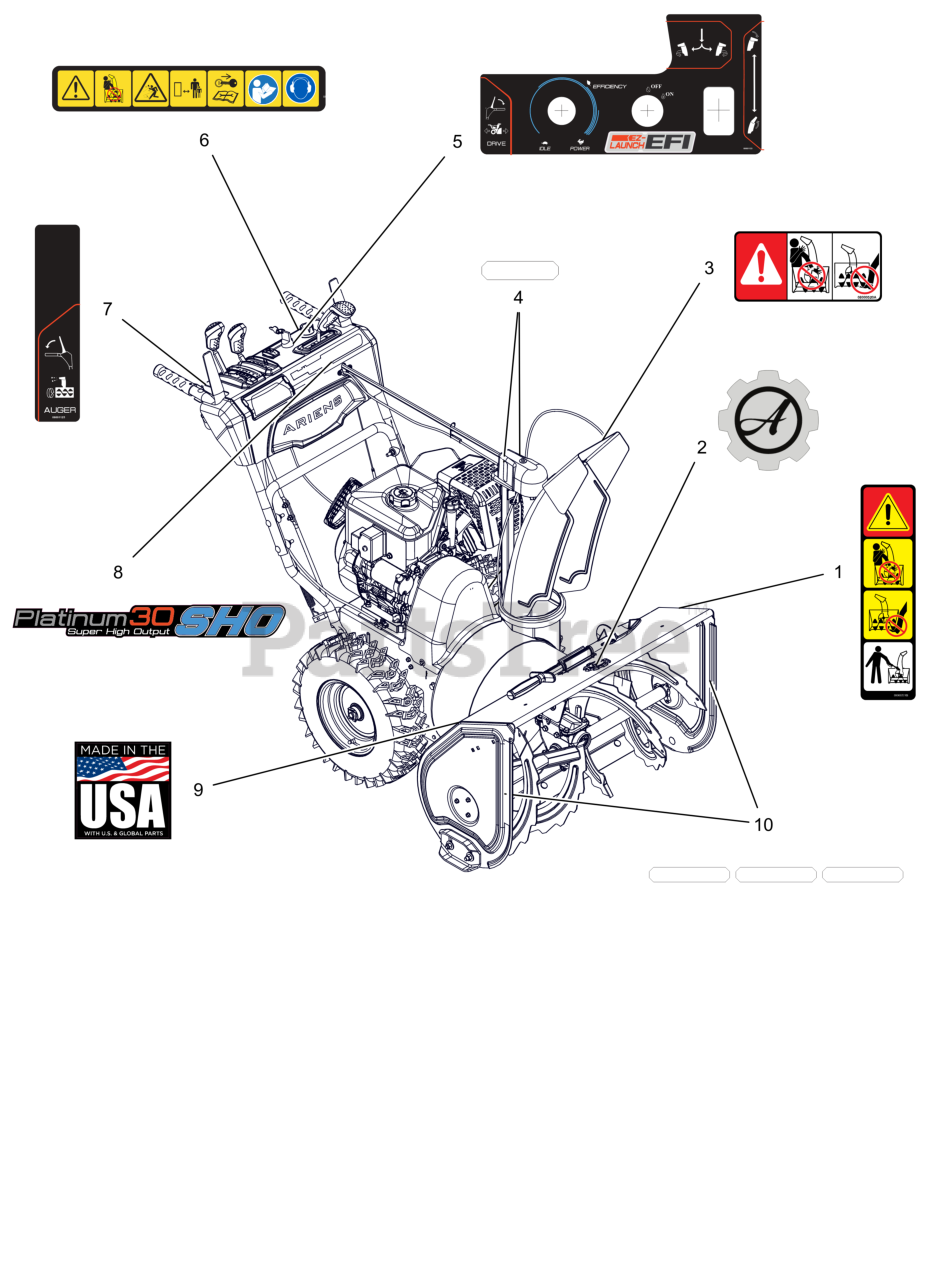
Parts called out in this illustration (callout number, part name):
1	DECAL, DANGER - ROTATING PARTS
2	DECAL, ARIENS - GEAR BADGE
3	DECAL, DANGER
4	DECAL,REFLECTIVE,GEAR COVER
5	DECAL, CONTROL - QT EFI W/GEL
6	DECAL,DASH - SAFETY/EFI
7	DECAL,CONTROL-RH CONTROL
8	DECAL, DASH, PLATINUM 30 SHO
9	DECAL, MADE IN USA
10	DECAL,REFLECTIVE,HOUSING
